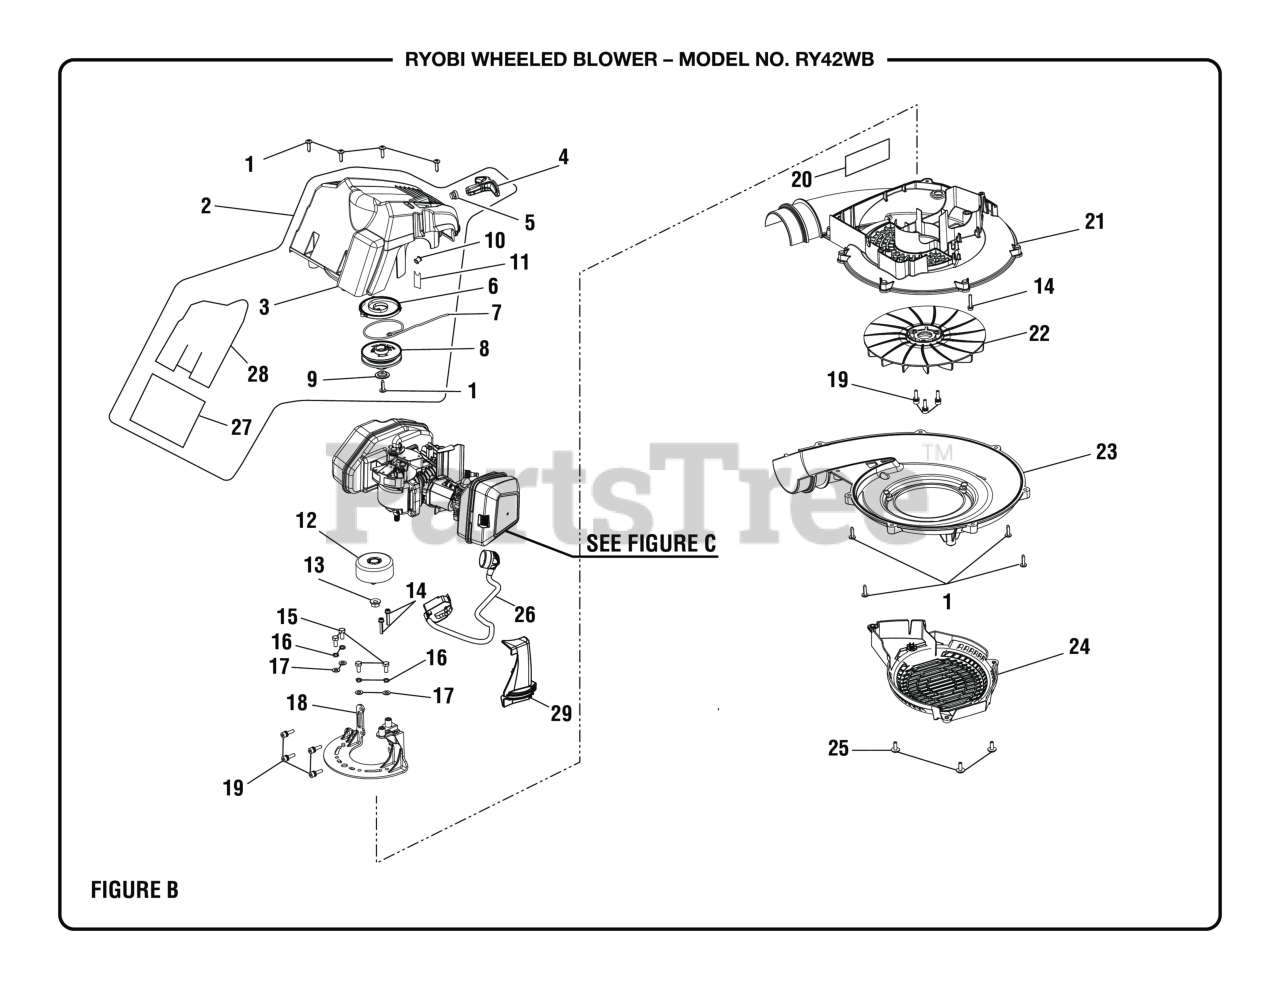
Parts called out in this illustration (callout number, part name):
1	Screw (10-14 x 19 mm, T25 Torx Truss Pan Hd. T.F.)
2	Engine Cover w/Starter Assembly
3	Motor Cover
4	Starter Grip
6	Spring & Container Assembly
7	STARTER ROPE 42 (PKG)
8	Starter Pulley
9	Starter Cap
11	Eyelet Support
13	Lock Nut (M8 x 1.25 in., Left Hand Threads)
14	Screw w/Washer (M5 x 25.4 mm, T25 Pan Hd. T.F.)
15	Screw (M6 x 14 mm, Hex Soc. Hd.)
16	Spring Washer (ID6.4 x 1.6t)
17	Washer (OD12.9 x ID6.6 x 1.2t)
18	Engine Mount
19	Screw w/Washers (M5 x 20 mm, Hex Soc. Hd.)
20	Heat Shield Tape
21	Inner Volute
23	Outer Volute
24	Intake Cover
25	Screw (#10-14 x 3/4 in, T25 Torx Pan Hd. T.F.)
26	Ignition Module
27	Foil Tape
28	Insulation
29	Cable Guide/Baffle Plate
